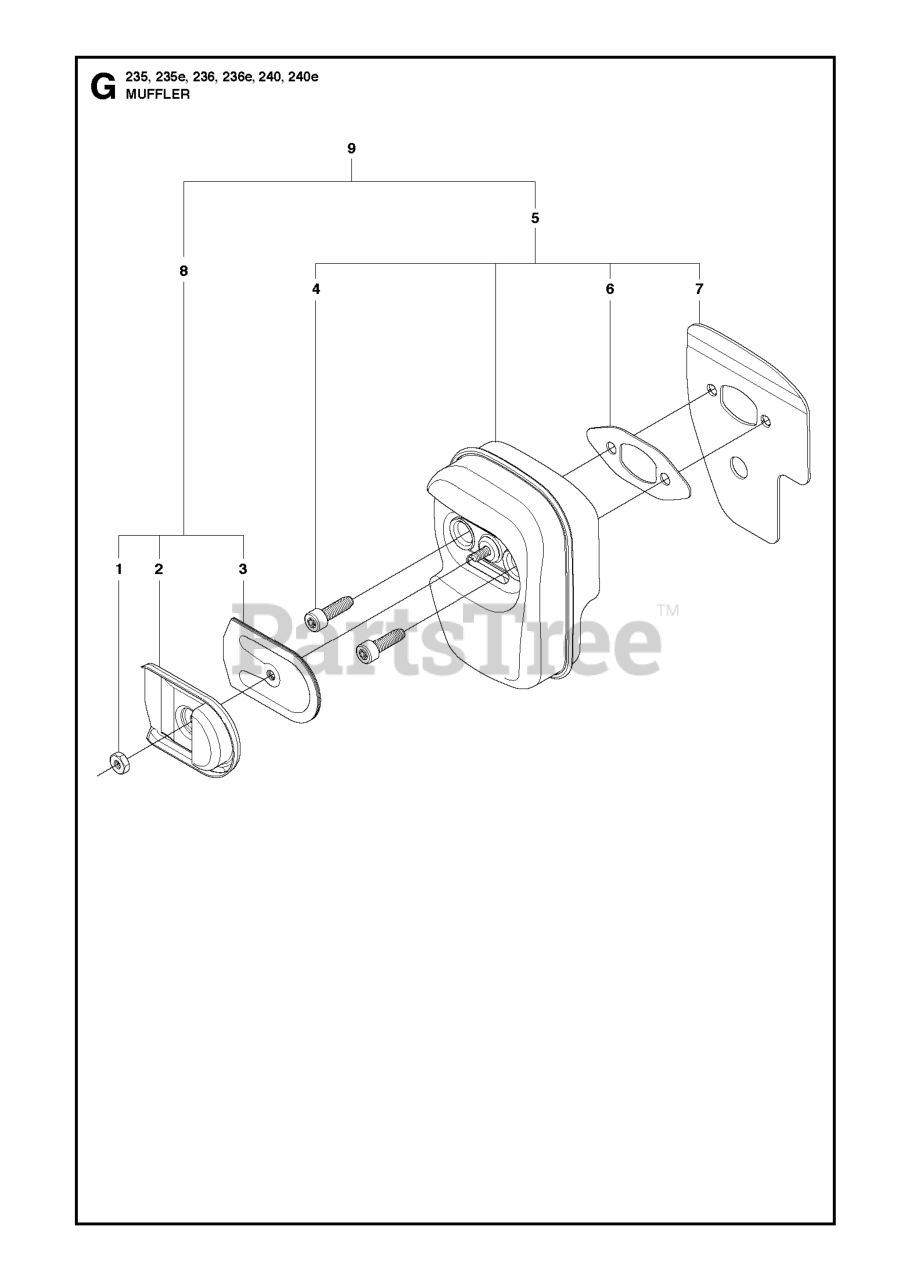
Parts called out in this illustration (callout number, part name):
1	NUT 10MM BRASS
2	EXHAUST PLATE
3	SCREEN ARRESTOR
4	SCREW MUFFLER
5	MUFFLER ASSY
8	KIT SPARK ARRESTOR
9	MUFFLER KIT
